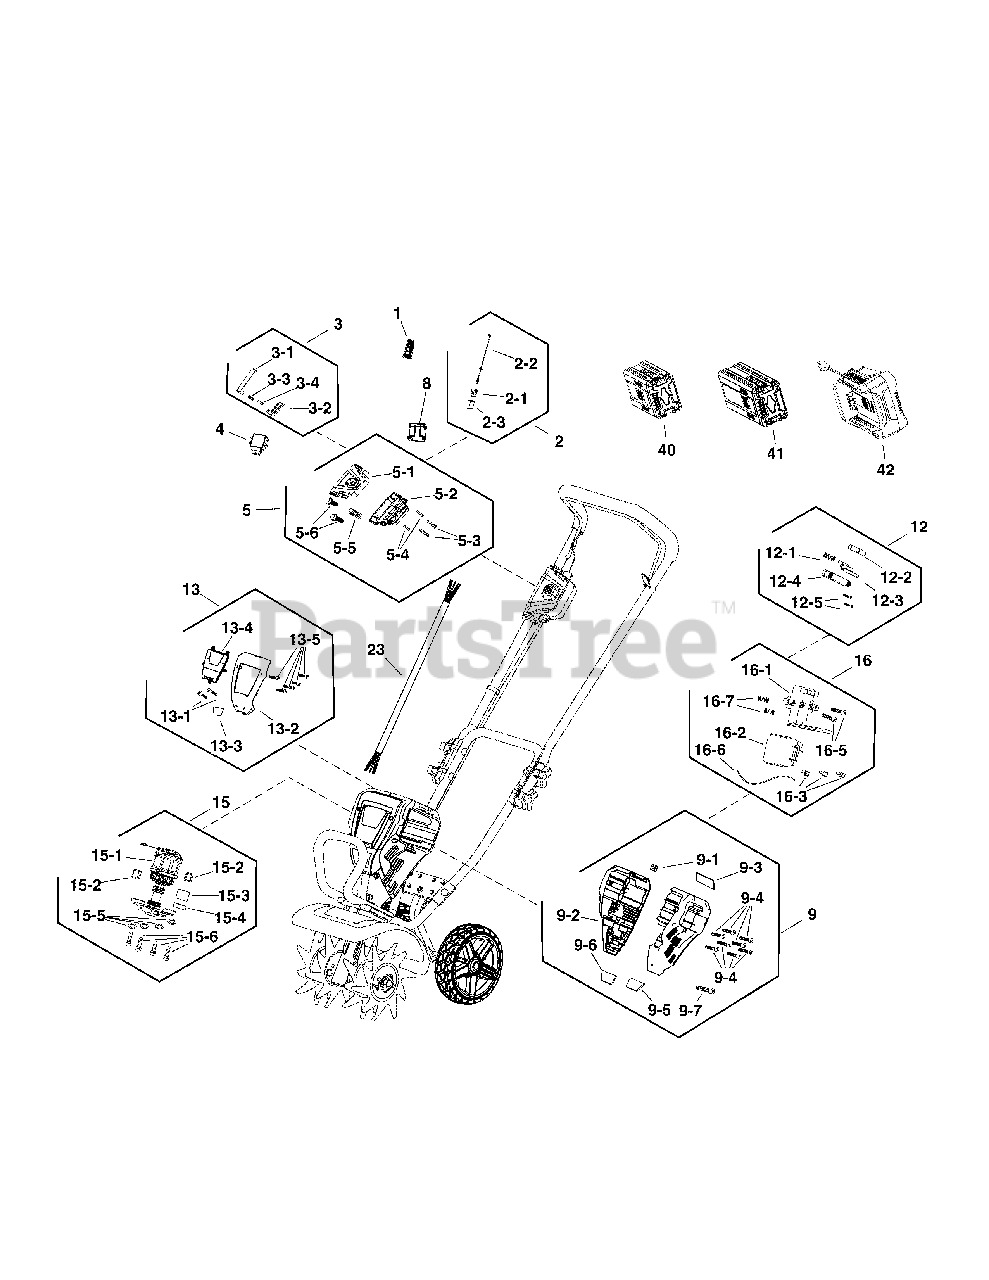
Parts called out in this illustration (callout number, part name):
2	KIT, CABLE ASSEMBLY
2-1	SPRING
2-2	CABLE, Bail
2-3	BLOCK
3	KIT, SLIDER ASSEMBLY
3-1	PLATE
3-2	BLOCK
3-3	SPRING
3-4	PIN
4	ADAPTER, HARNESS
5	KIT, STARTER ASSEMBLY
5-1	COVER, Bottom
5-2	COVER, Bottom
5-3	SPRING
5-4	SCREW
5-5	CLAMP
5-6	SCREW
8	SWITCH INSERT
9	KIT, MOTOR HOUSING
9-1	NUT
9-2	HOUSING, Right
9-3	LABEL
9-4	SCREW
9-5	SPONGE
9-6	SPONGE
9-7	SCREW
12	KIT, BATTERY RELEASE BUTTON
12-1	SPRING
12-2	PIN
12-3	BUTTON, Battery Releasee
12-4	PAD
12-5	SCREW
13	KIT, TOP COVER
13-1	SCREW
13-2	COVER, DECORATIVE
13-3	LABEL
13-4	COVER, Battery
13-5	SCREW
15	KIT, MOTOR ASSEMBLY
15-1	MOTOR
15-2	SEAL
15-3	AXLE SLEEVE
15-4	CLAMP
15-5	WASHER, Spring
15-6	BOLT
16	KIT, PCB ASSEMBLY
16-1	BATTERY HOLDER
16-2	PCB
16-3	TERMINAL
16-5	SCREW
16-6	WIRE, Yellow
16-7	SPRING
23	WIRING HARNESS
40	* BATTERY, 2.0, 82V NA
41	* BATTERY, 4.0, 82V NA
42	* CHARGER, Battery, NA
